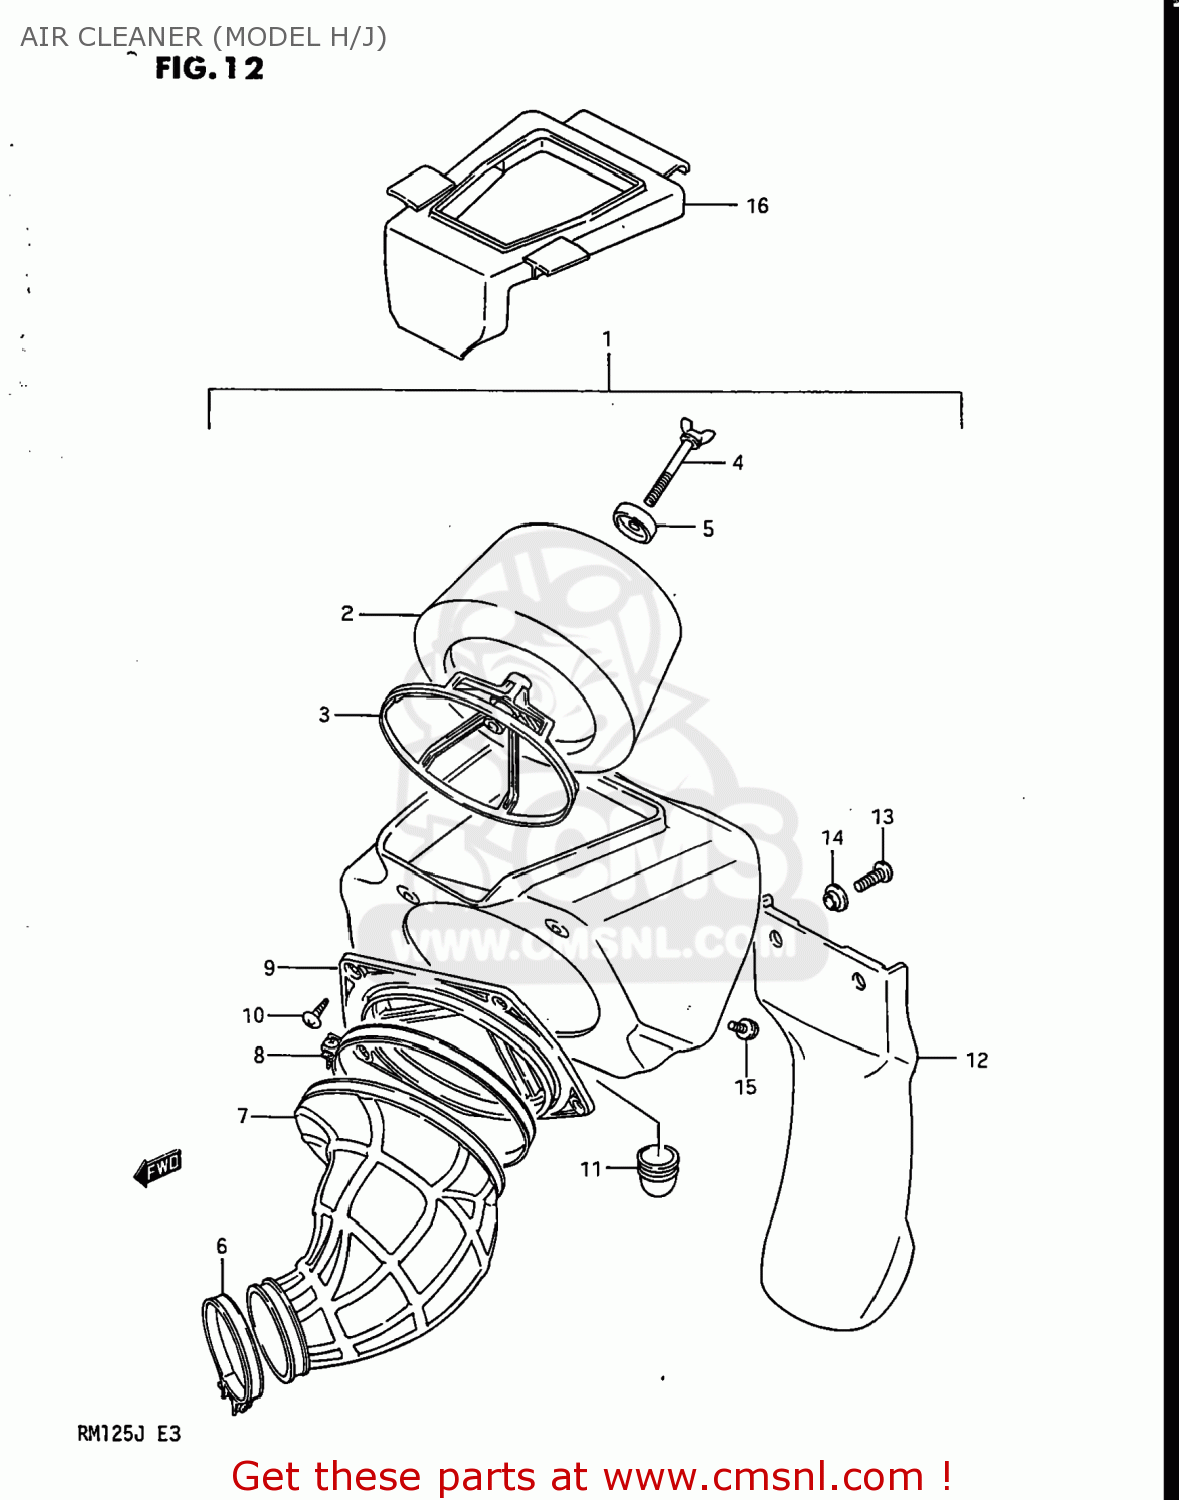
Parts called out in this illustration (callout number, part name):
1	CLEANER ASSEMBLY,AIR
2	FILTER,AIR CLEANER
3	HOLDER,FILTER
4	BOLT,WING
5	WASHER,AIR CLEANER
6	CLAMP
7	TUBE,AIR CLEANER OUTLET
8	CLAMP
9	HOLDER,FILTER
10	SCREW
11	HOSE,AIR CLEANER DRAIN
12	GUARD,MUD
13	SCREW
14	COLLAR
15	BOLT
16	GUARD,MUD
